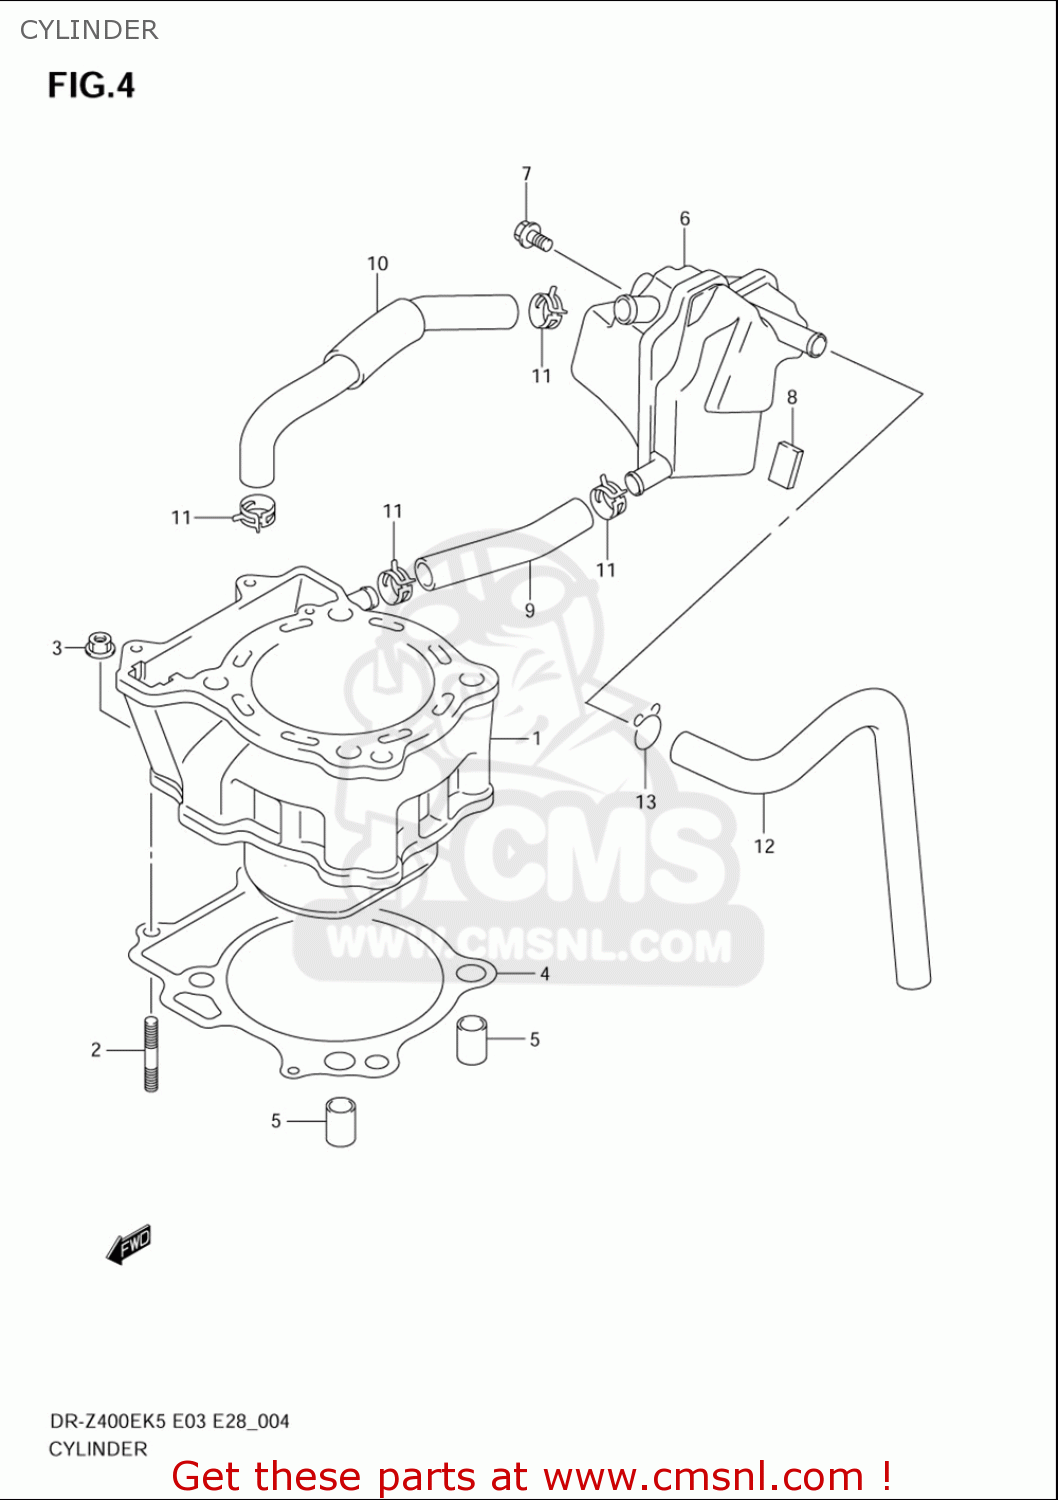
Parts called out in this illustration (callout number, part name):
1	CYLINDER
2	STUD BOLT
3	NUT
4	GASKET,CYLINDER (NAS)
5	PIN
6	TANK,OIL RETURN
7	BOLT
8	PROTECTOR(170X95X3.0)
9	HOSE,BREATHER
10	HOSE,BREATHER
11	CLIP
12	HOSE,BREATHER
13	CLIP
